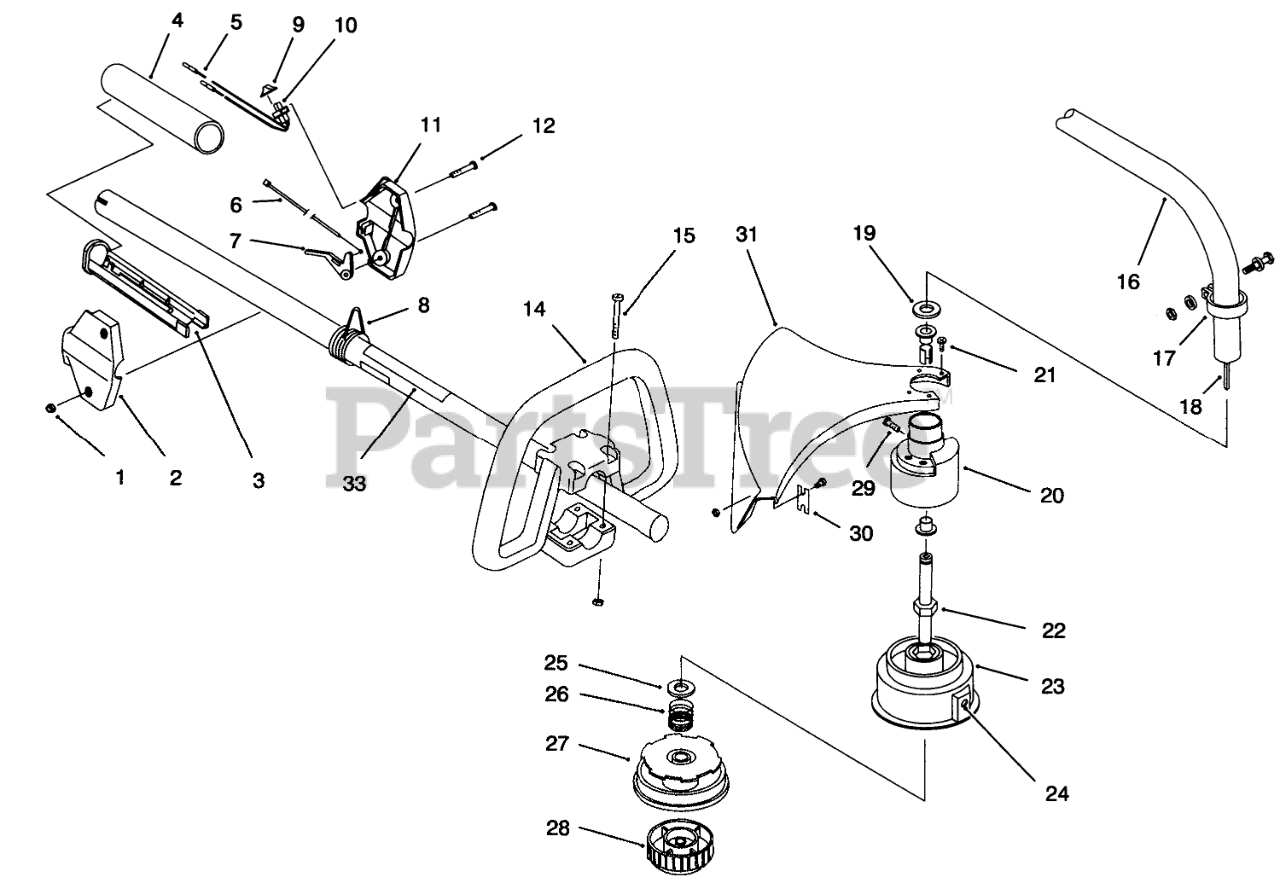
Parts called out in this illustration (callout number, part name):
1	NUT-LOCK, NI
2	RH HOUSING
3	TROUGH 1"
4	GRIP - RUBBER
5	LEAD WIRE ASM
6	THROTTLE CABLE
7	THROTTLE LEVER
8	Clip-Shoulder Strap
9	SWITCH COVER
10	SWITCH
11	LH HOUSING
14	HANDLE W/HARDWARE
15	HARDWARE - HANDLE
16	ASM - DRIVE SHAFT HSG
17	CLAMP ASM - UPPER
18	Drive Shaft
20	BUSHING HSG ASM
21	GUARD MTG SCREW ASM
22	Shaft-Spool
23	OUTER SPOOL EYELET ASM
24	EYELET
25	RETAINER WASHER(SET OF 10)
26	SPRING
27	REEL - INNER
28	Assy.-Bump Head
29	ANTI-ROTATION SCREW
30	Blade Asm.
31	Guard and Blade Asm. (Incl. Ref. #30)
33	Decal-Safety Symbol
